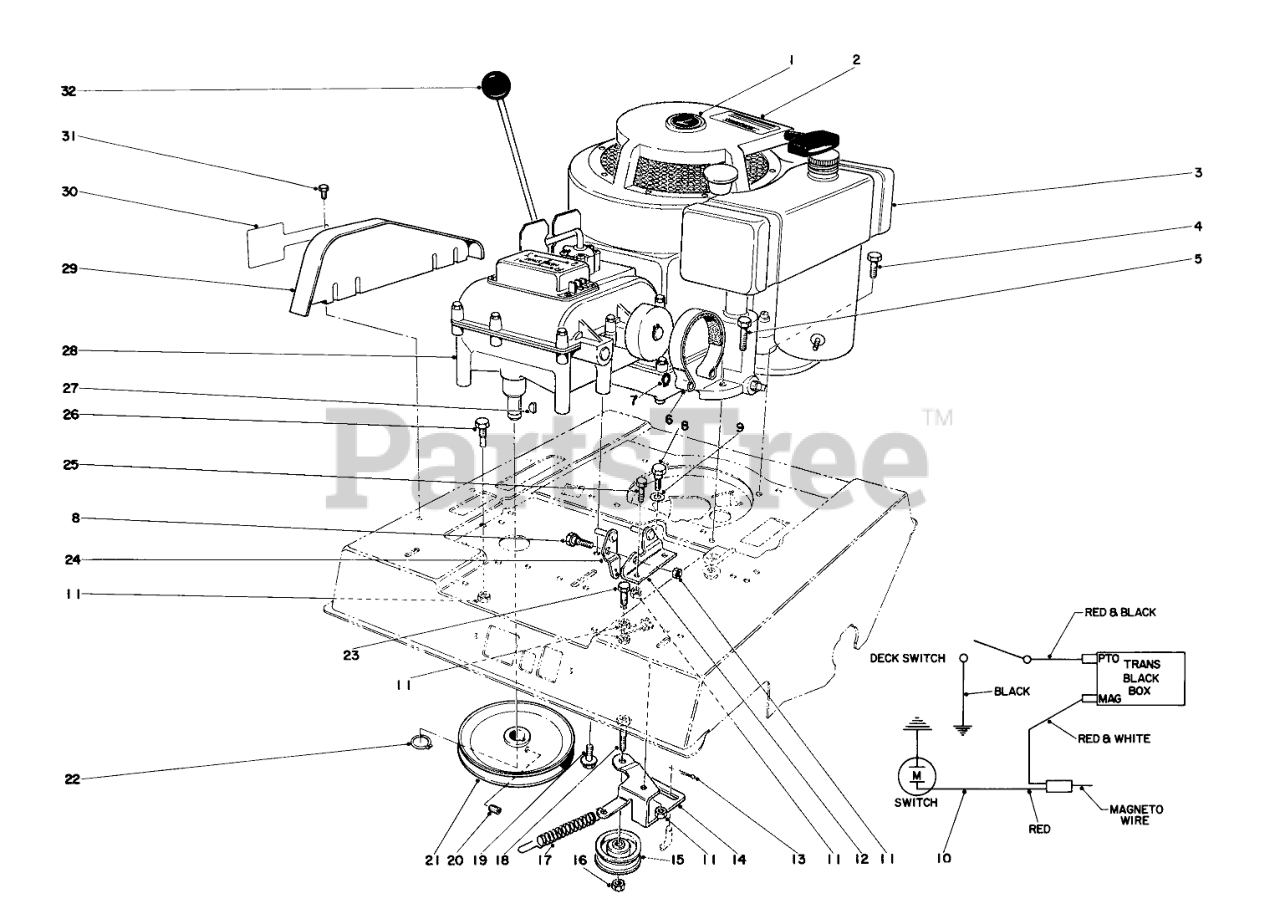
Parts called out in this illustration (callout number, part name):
1	Decal
2	Caution Decal
3	Engine
4	SCREW-HH
5	SCREW-HH
6	Brake Band
7	RING-GRIP
8	Screw
9	Washer
10	Wire Harness
11	NUT-LOCK, CONE
12	Bracket
13	PIN-COTTER
14	Idler Lever
15	PULLEY IDLER
16	Locknut
17	Clutch Spring
18	Capscrew
19	SCREW-HHF
20	SCREW-SET
21	Pulley
22	RING-SNAP, EXTERNAL
23	SCREW-HH
24	Pivot
25	SCREW-HH
26	Screw
27	KEY-WOODRUFF
28	Transmission
29	Chain Guard
30	Decal Shift Pattern
31	SCREW-HWH
